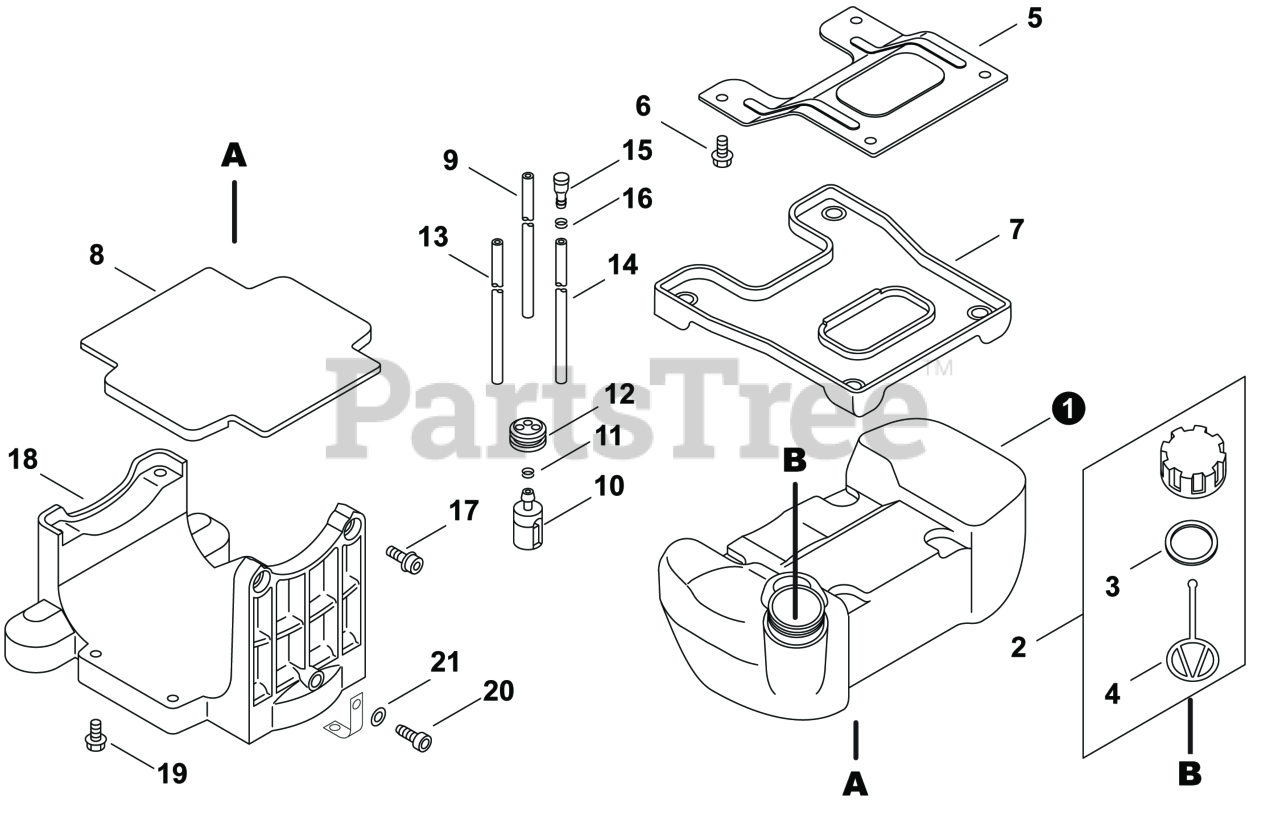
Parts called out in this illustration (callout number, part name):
1	TANK, FUEL
2	CAP ASSY, FUEL
3	GASKET, FUEL CAP
4	CONNECTOR, CAP L= 100 MM
5	BRACKET, FUEL TANK
6	BOLT 5×12
7	CUSHION, UPPER
8	CUSHION, FUEL TANK
9	PIPE, FUEL 3×6×230
10	FILTER, FUEL
11	CLIP Ø6.5 MM
12	GROMMET, FUEL
13	PIPE, FUEL 3×6×120 CLEAR
14	PIPE, FUEL 3×6×120 BLACK
15	VENT ASSY
16	CLIP Ø6.5 MM
17	BOLT, FLANGE 5X25
18	PLATE, MOUNTING
19	BOLT 5×20
20	SCREW TAPPING 5×16
21	WASHER, FLAT 5.5×10×0.8
